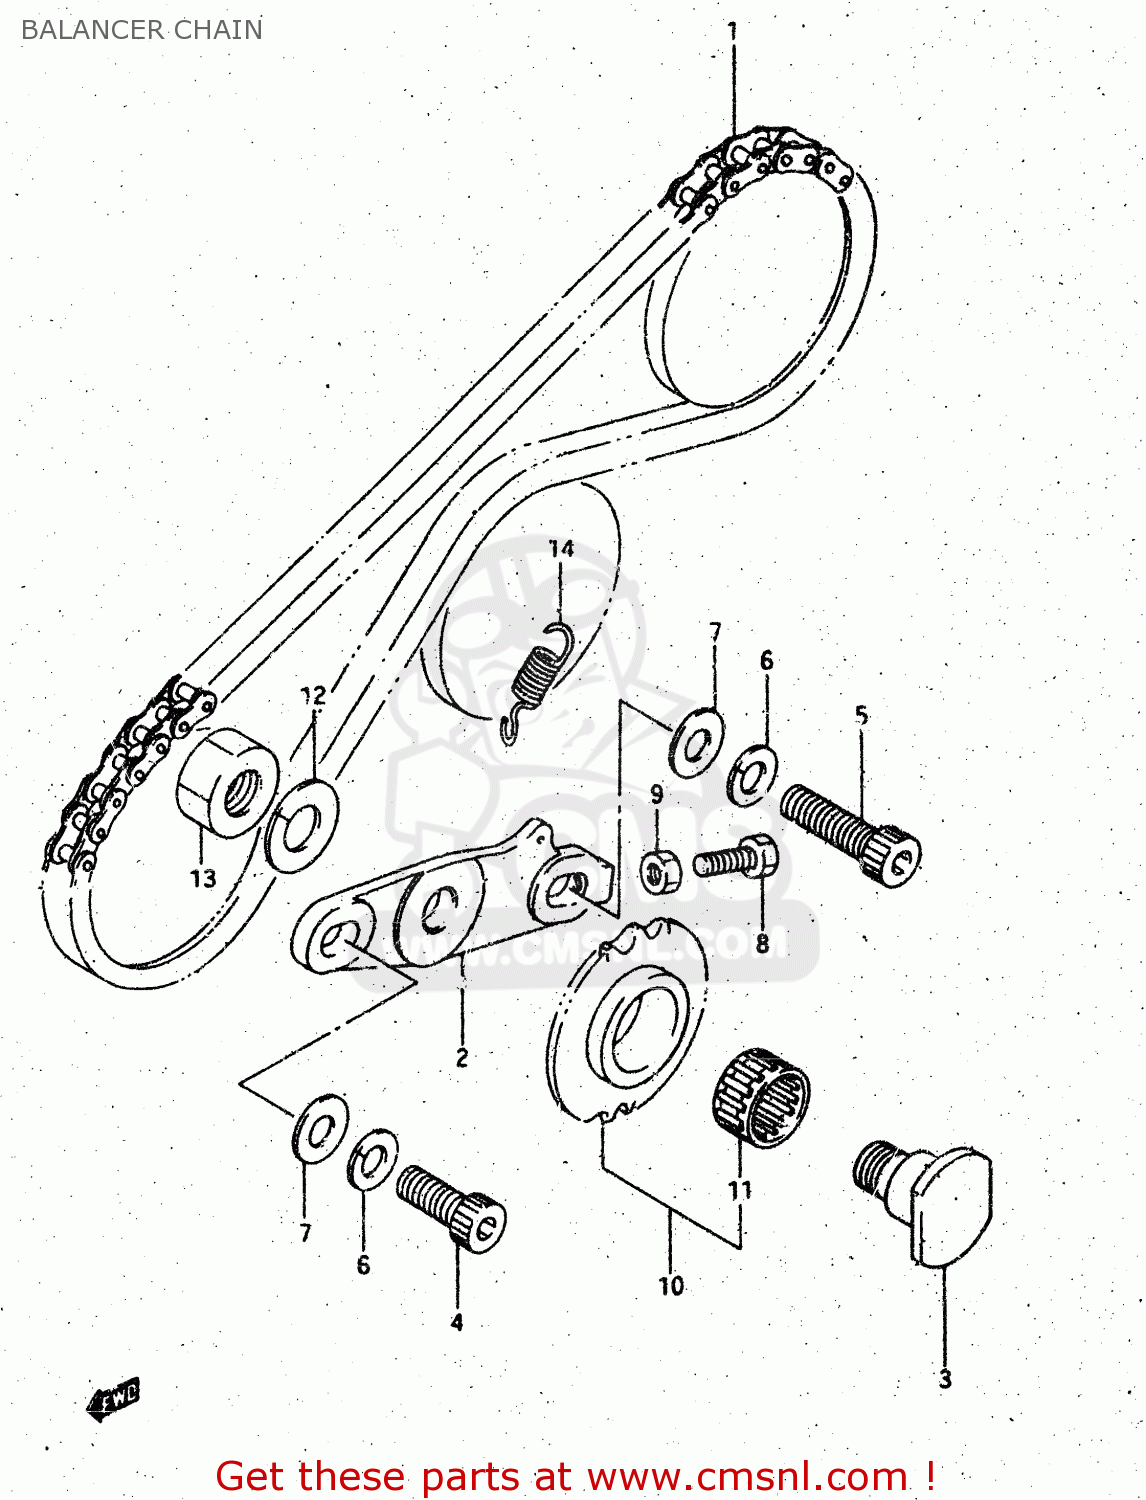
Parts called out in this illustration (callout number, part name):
1	CHAIN,BALANCER
2	BRACKET,BALANCER CHAIN
3	SHAFT,BALANCER CHAIN TENSIONER
4	BOLT(8X22)
5	BOLT, REAR (8X30)
6	LOCK WASHER
7	WASHER
8	BOLT 5X20
9	NUT
10	SPROCKET,BALANCER CHAIN
11	BEARING(17X23X12)
12	WASHER,LOCK 12
13	NUT
14	SPRING
